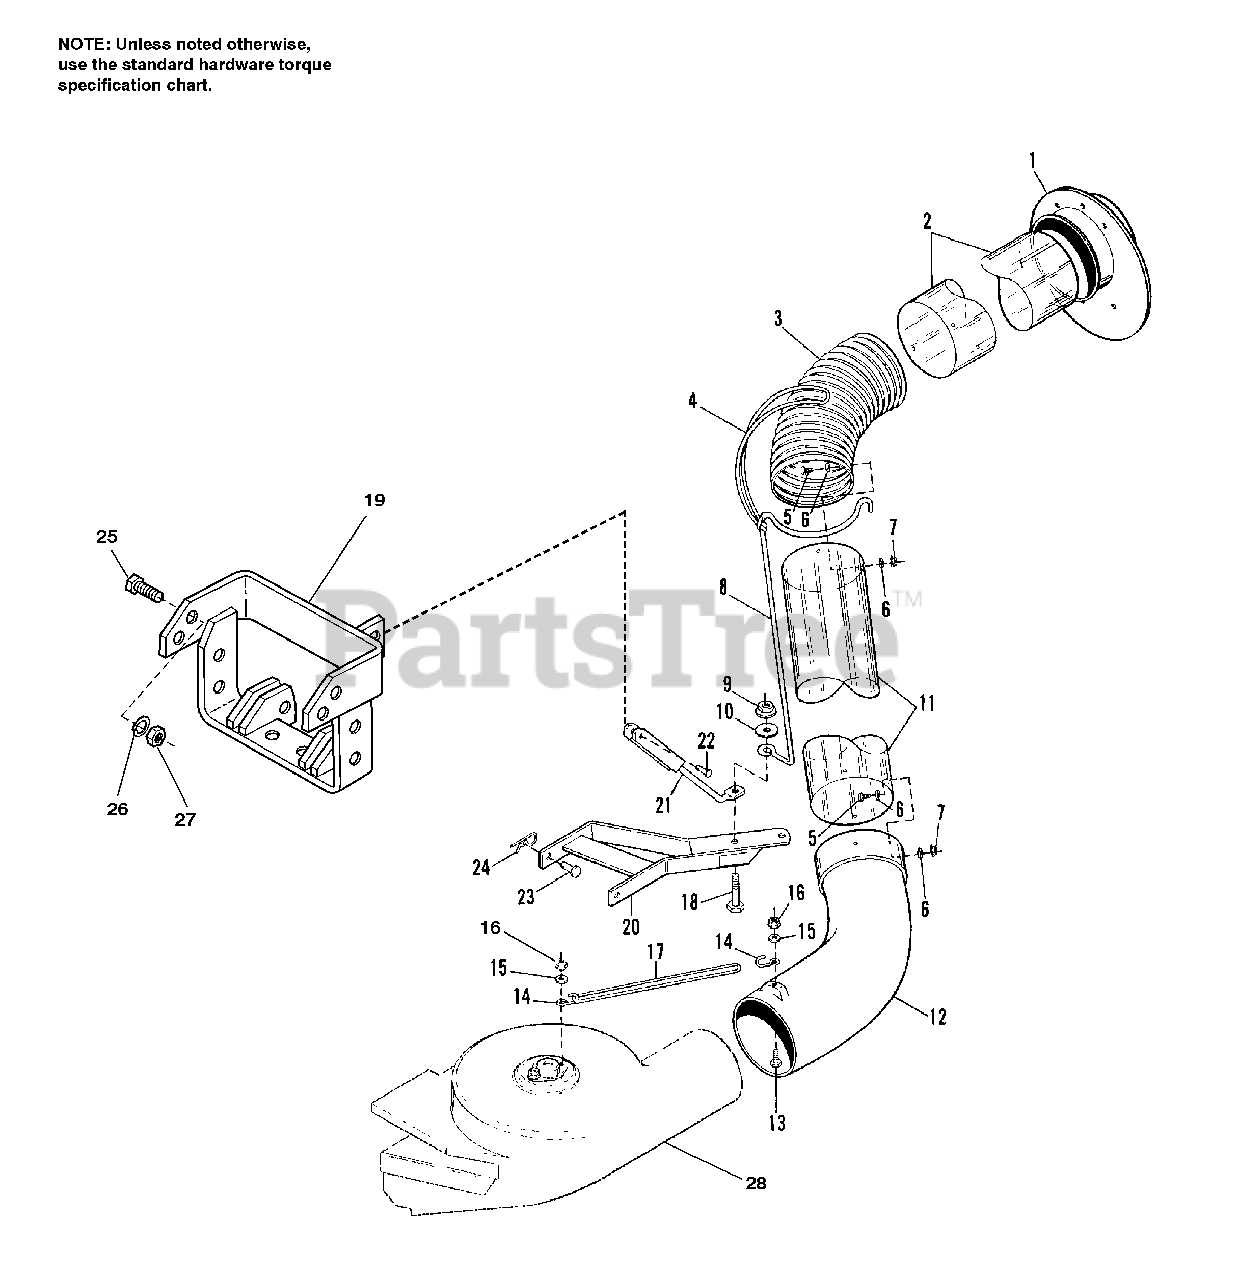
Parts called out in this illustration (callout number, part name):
1	CONNECTOR, Cart
3	HOSE, 6" Dia.
4	STRAP, Black Rubber
5	CAPSCREW, Truss Hd, #10-32 x 1/2
6	WASHER, Plain, 3/16
7	NUT, Hex Flange, #10-32
8	SUPPORT, Tube
9	NUT, Hex Flange, 1/2-13
10	WASHER, 1/2
11	TUBE & DECAL ASSEMBLY, 48" Models
11	TUBE & DECAL ASSEMBLY, 60" Models
12	ELBOW, 6" Dia.
13	CAPSCREW, Hex Hd, 5/16-18 x 5/8
15	WASHER, 5/16
16	NUT, Hex Flange Hd, Whiz Lock, 5/16-18
17	STRAP, Rubber
18	CAPSCREW, Hex Hd, 1/2-13 x 2
19	HITCH ASSEMBLY
20	DRAWBAR ASSEMBLY
21	SUPPORT ASSEMBLY
22	PIN, Round Head
23	PIN, Clevis
24	CLIP, Hairpin
25	CAPSCREW, Hex Hd, 1/2-13 x 1-1/4
26	WASHER, Lock, 1/2
27	NUT, Hex, 1/2-13
28	TURBO ASSEMBLY (Shown for Reference Only)
